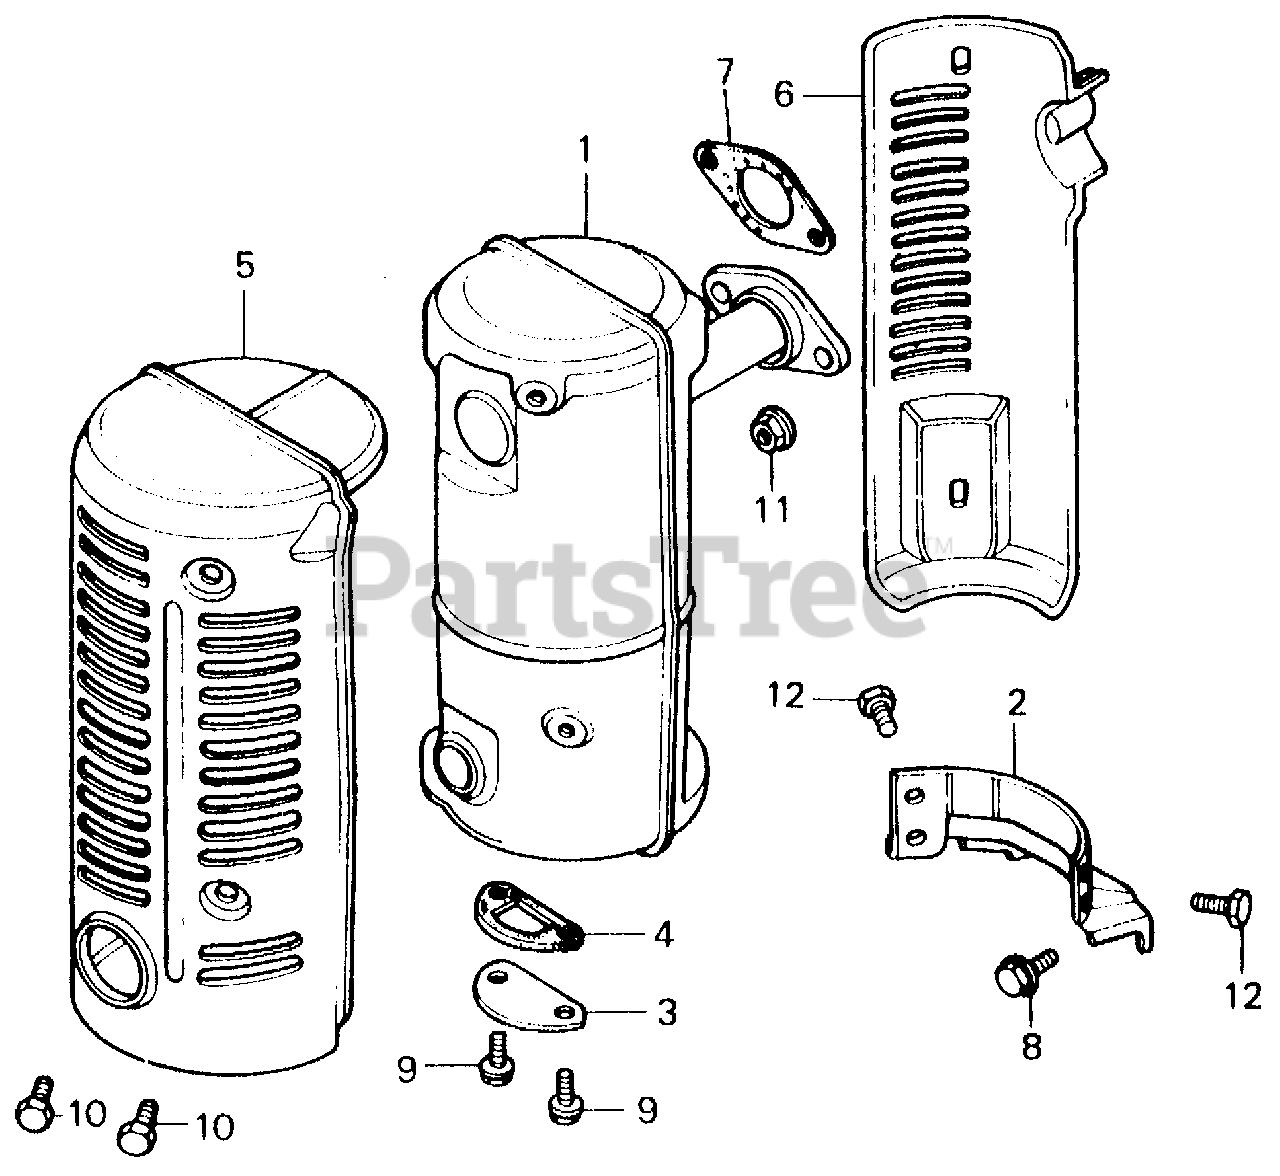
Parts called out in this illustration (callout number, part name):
1	MUFFLER ASSY.
2	STAY, MUFFLER
3	LID, MUFFLER
4	GASKET, MUFFLER LID
5	PROTECTOR A, MUFFLER
6	PROTECTOR B, MUFFLER
7	GASKET, MUFFLER
8	BOLT, FLANGE (8X16)
9	BOLT, HEX. (6X12)
10	BOLT, HEX. (6X6)
11	NUT, FLANGE (8MM)
12	BOLT, FLANGE (6X10)
